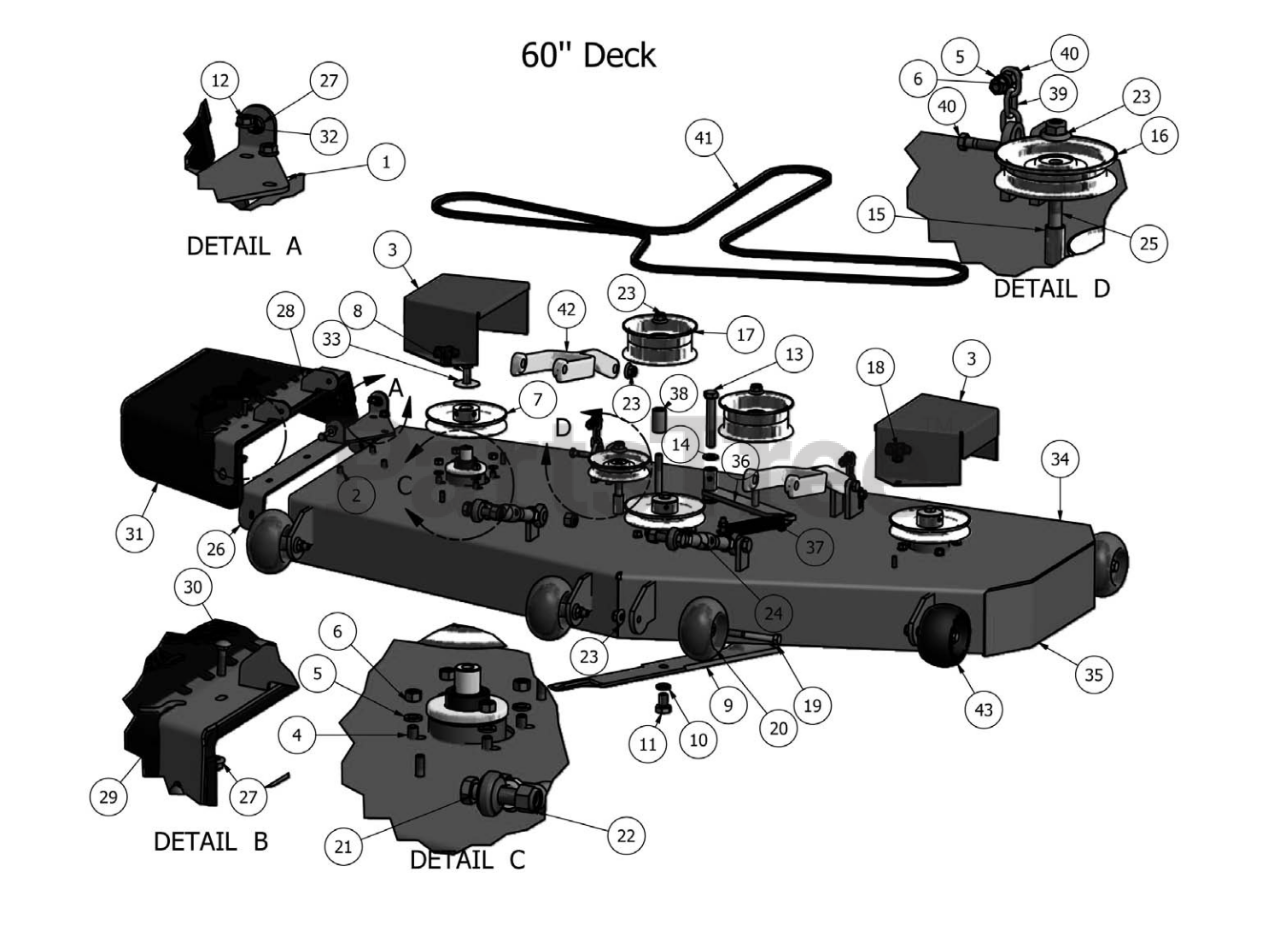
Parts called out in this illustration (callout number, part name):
1	Discharge Chute Hanger (deck mounted)
2	3/8" x 3/4" Hex Bolt
3	Pulley Cover
4	3/8" x 1 1/4" Hex Bolt
5	3/8" Lock Washer
6	3/8" Hex Nut
7	6 1/4" Drive Pulley
8	1/2" x 1 1/2" Hex Bolt
9	60 Inch Fusion Blade
10	5/8" Lock Washer
11	5/8" x 1 1/2" Grade 8 Bolt
12	3/8" Flange Nut
13	5/8" x 4" Hex Bolt
14	.635 ID Plastic Washer
15	Pulley Spacer
16	4 3/4" Idler Pulley
17	5 3/4" Deck Idler Pulley
18	5/16" Knob
19	1/2" x 4" Bolt (Grade 8)
20	Anti-Scalp Rollers (Roller Only)
21	5/8" x 2 1/2" Hex Bolt
22	5/8" Nylock (1/2 Jam)
23	1/2-13 Nylon Flange Nut-Orange
24	Turnbuckle
25	1/2 x 3 1/2 Flange Bolt Grade 8
26	60" Lower Hanger
27	5/16" Flange Nut
28	Rubber Discharge Chute Assembly
29	60" Upper Hanger Plate
30	5/16" x 1 1/4" Carriage Bolt
31	Rubber Discharge Chute (Rubber Only)
32	5/16" x 1" Hex Bolt
33	Cup Washer
34	60" ZT Deck (Shell Only)
35	60" Complete ZT Deck
36	Deck Idler Bracket
37	Deck Idler Spring
38	1.75" x .5" O.D. Spacer
39	ZT Deck Hanger Assembly
40	3/8" x 1 1/2" Hex Bolt
41	60" ZT Deck Belt
43	Anti-Scalp Roller Assembly
